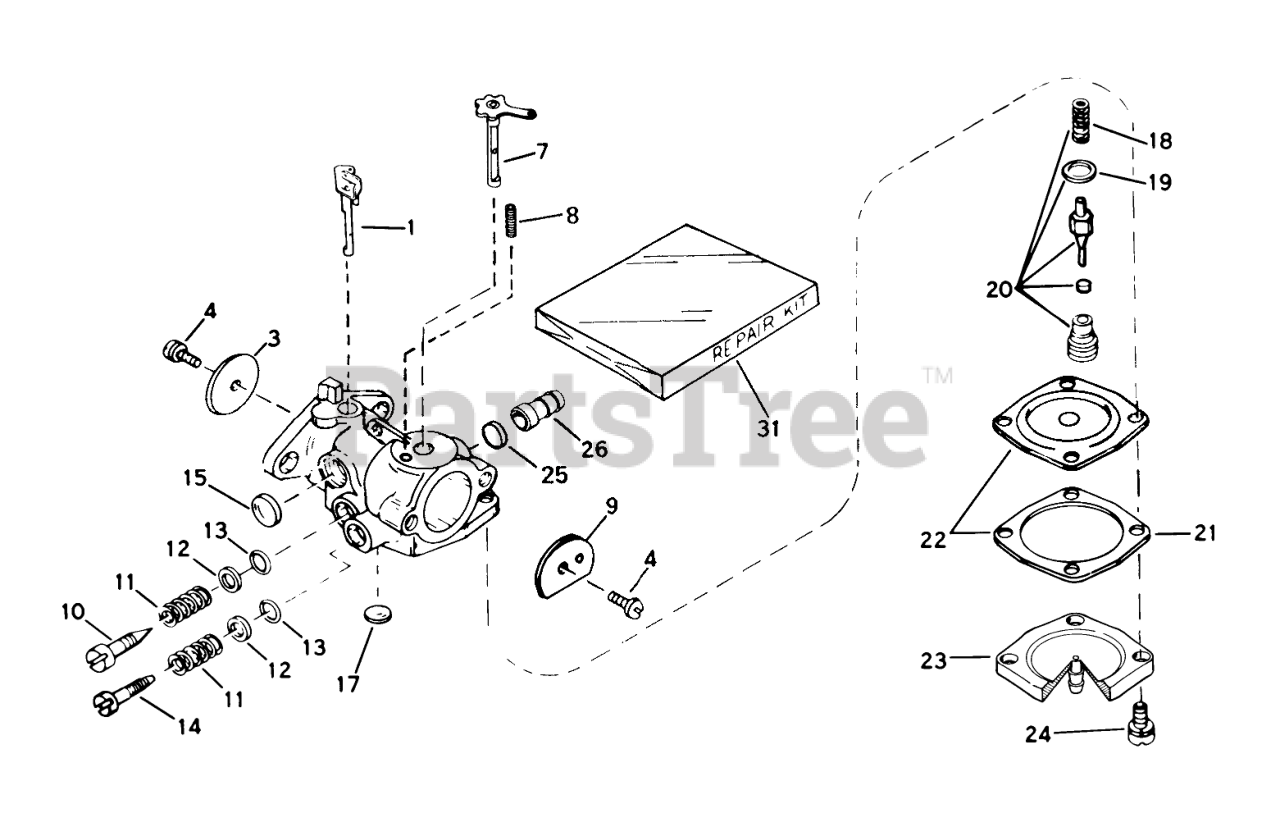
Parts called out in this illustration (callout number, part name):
1	Shaft/Lever-Throttle
3	Shutter-Throttle
4	Screw-Shutter
7	Shaft & Lever Assembly
8	Spring-Positioning, Choke
9	Shutter-Choke
10	Screw-Idle Adjustment
13	"O"Ring
14	Screw Main Adjustment
15	Plug-Welch, Idle Mixture Well
17	Plug Welch
18	Spring-Valve
19	Gasket-Valve Seat
20	Inlet Needle, Seat, Spring & Gasket Assy. (Incl. #18 & 19)
21	Gasket-Diaphragm
22	Diaphragm Assy. (Incl. #21)
23	Cover-Diaphragm
26	Fitting-Fuel
31	Kit-Repair
